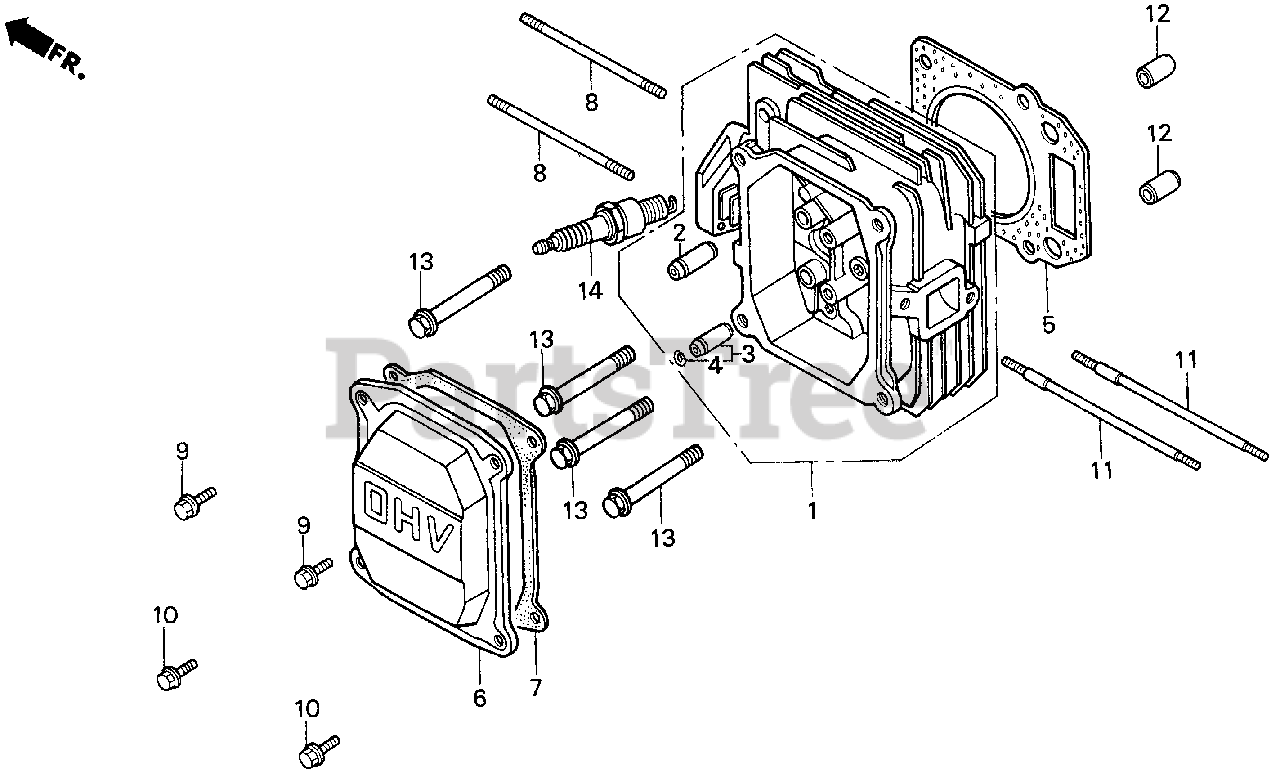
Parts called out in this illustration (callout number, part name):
1	CYLINDER HEAD
2	GUIDE, VALVE (OS)
3	GUIDE, EX. VALVE (OS)
4	CLIP, VALVE GUIDE
5	GASKET, CYLINDER HEAD
6	COVER, HEAD
7	GASKET, CYLINDER HEAD COVER
8	BOLT, STUD (6X82)
9	BOLT, FLANGE (6X14)
10	BOLT, FLANGE (6X12) (CT200)
11	BOLT, STUD (6X109)
12	PIN A, DOWEL (10X16)
13	BOLT, FLANGE (8X50)
14	SPARK PLUG (BPR4ES) (NGK)
14	SPARK PLUG (W14EPR-U) (DENSO)
14	SPARK PLUG (BPR5ES) (NGK)
14	SPARK PLUG (W16EPR-U) (DENSO)
14	SPARK PLUG (BPR6ES) (NGK)
14	SPARK PLUG (W20EPR-U) (DENSO)
